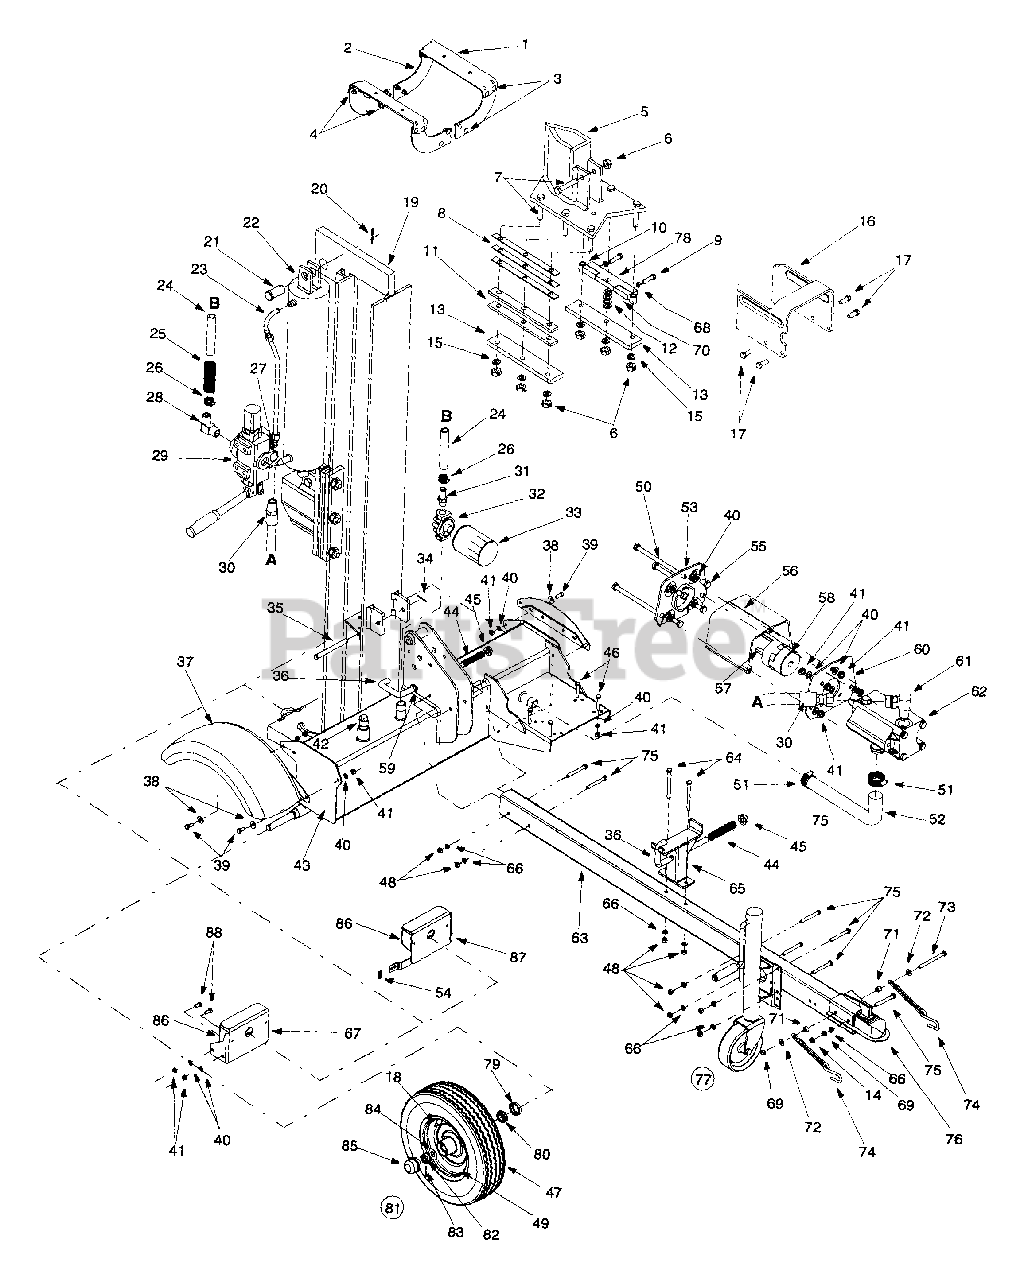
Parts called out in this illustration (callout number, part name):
4	Flanged Lock Nut, 3/8-16
7	Hex Head Screw, 1/2-20 x 2.75
10	Spacer
12	Flat Washer, .531 ID x .94 OD
14	Hex Jam Nut, 3/8-16
15	Lock Washer, 1/2
17	Hex Cap Screw, 3/8-16 x 1
18	Valve
22	Kit Seal 5.0" for Best Metals cylinder 718-0313
22	Hydraulic Cylinder
22	Kit Seal 5.0" for XINGHUI cylinder 718-0313A
22	Kit Seal 5.0" for ENERGY cylinder 718-0313A
23	Hydraulic Tube
24	Return Hose, 3/4 x 44 Lg
25	Hose Guard
27	Tube Adapter
28	Return Elbow
30	High Pressure Hydraulic Hose
32	Filter Head
33	Oil Filter
39	Hex Cap Screw, 5/16-24 x .75
40	Lock Washer, 5/16
41	Hex Nut, 5/16-24
42	Pipe Plug
46	Hex Cap Screw, 5/16-24 x 1.75
47	Tire, 16 x 4.8
48	Hex Nut, 3/8-16
49	Rim Assembly (Oyster Gray)
50	Hex Cap Screw, 5/16-24 x 5.25
52	Suction Hose
55	Hex Cap Screw, 5/16-24
56	Coupling Shield
57	Key, 1/4 x 2
58	Flex Coupling
59	Flat Washer, .63 x .93 x .060
62	Gear Pump (16 GPM)
64	Hex Screw, 3/8-16 x 4.0
69	Hex Lock Nut, 3/8-16
70	Adjustable Gib, 5/8 x 5/8 x 2
72	Flat Washer, 3/8" ID x .87" OD
73	Hex Bolt, 3/8-16 x 4.25
74	Chain
75	Hex Bolt, 3/8-16 x 3
76	Hitch Coupler
77	Adjustable Jack Stand Assembly
79	Bearing Seal
80	Tapered Bearing
81	Wheel Assembly
82	Slotted Nut, 3/4-16
84	Flat Washer, .760 ID x .500 OD
86	Tail Light Assembly
